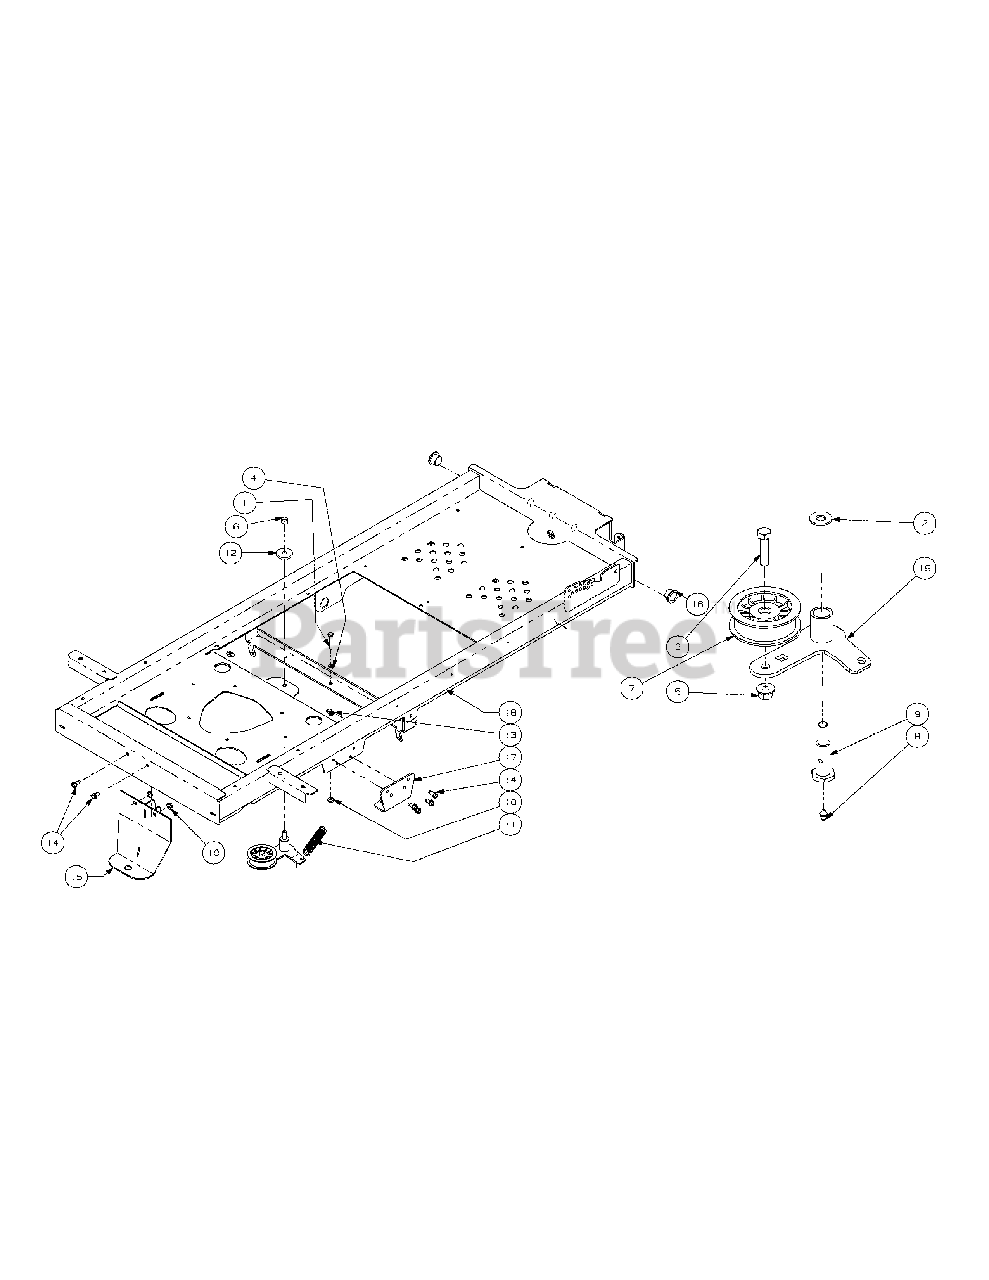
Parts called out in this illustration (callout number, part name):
1	Hex Cap Screw, 5/16-18 x 1-3/4
2	Flat Washer, 3/8 zinc
3	Hex Cap Screw, 3/8-16 x 1-1/2
4	Hex Nut, 5/16-18
5	Hex Nut, 3/8-16 Flange Lock
6	Nylock Nut, 7/16-14
7	Flat Idler Pully w/ adaptor
8	Grease Fitting, 1/4-28 x 3/16
9	Shoulder Bolt
10	Nut, 5/16-18, Hexflange Lock
11	Extension Spring, .865 OD x 4.68 lg
12	Flat Washer, 7/16 ID x 1.75 OD
13	U-Nut, 1/4-20
14	Self Tapping Screw 5/16-18 x .750
16	Bronze Bushing, 1.00 ID x 1.50 OD
17	Transmission Mounting Bracket
18	Frame Assembly Weldment
19	Idler Arm Assembly includes:
